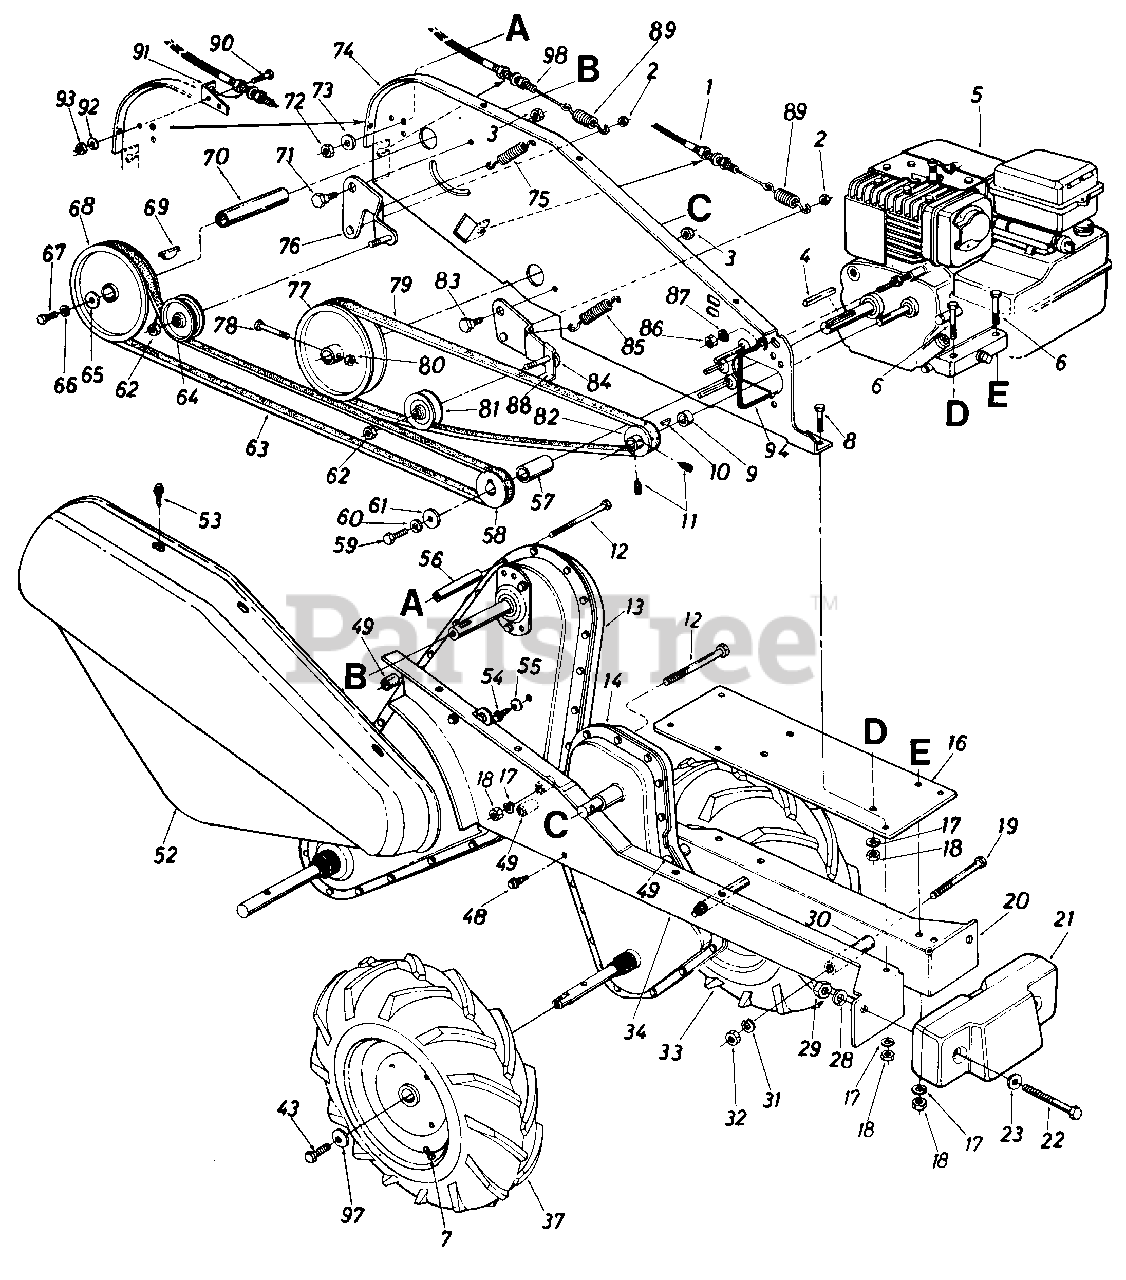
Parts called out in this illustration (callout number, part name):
1	Clutch Control Cable
2	Hex Cent. L-Nut 1/4-20 Thd.
3	Hex Cent. L-Nut 3/8-16 Thd.
4	Sq. Key 3/16" Dia. x .75
5	Engine
6	Hex Bolt 5/16-18 x 1.50" Lg.
7	Air Valve
8	Hex Bolt 5/16-18 x .75" Lg.
9	Spacer .51" I.D. x 3/4" O.D. x .39" Lg.
10	Hi-Pro Key #5 Woodruff
11	Set Scr. 1/4-28 x .25" Lg.
12	Hex Bolt 5/16-18 x 3.0" Lg.
18	Hex Nut 5/16-18 Thd.
19	Hex Bolt 3/8-24 x 3.0" Lg.
22	Hex Bolt 1/2-13 x 4.0" Lg.
23	Fl-Wash. 1/2" I.D. x 1.0" O.D.
28	L-Wash. 1/2" I.D.
29	Hex Nut 1/2-13 Thd.
30	Spacer 3/8" I.D. x 5/8" O.D. x 2.18" Lg.
31	L-Wash. 3/8" I.D.
32	Hex Nut 3/8-24 Thd.
33	Comp. Wheel Ass'y. L.H.
48	Hex Wash. Self-Tap Scr. 5/16-24 x .50" Lg.
49	Spacer 5/16" I.D. x 16 Ga. x.96" Lg.
54	Hex Wash. S-Tap Scr. 1/4-20 x 3/8" Lg.
55	Bell-Wash. 1/4" I.D.
56	Spacer 3/8" I.D. x 1/2" O.D. x 2.0" Lg.
57	Spacer 3/4" I.D. x 1.12" O.D. x 1.56" Lg.
58	1/2" "V"-4L Pulley 3/4n I.D. x 2.59" O.D.
59	Hex Bolt 5/16-24 x 1.0" Lg.
60	L-Wash. 5/16" I.D.
61	Fl-Wash. 5/16" I.D. x 1.25" O.D.
62	Hex L-Nut 3/8-24 Thd.
63	"V"-Belt
64	Fl-ldler Pulley 3.75" O.D. x 3/8" 1.D.
65	Fl-Wash. .25" I.D. x .93" O.D. x .120
66	L-Wash. 1/4" I.D.
67	Hex Bolt 1/4-28 x .75" Lg.
68	Split Pulley 6" Dia. x 5/8" I.D.
69	Hi-Pro Key
70	Spacer
71	Shld. Bolt 1/2" Dia. x .210n Lg.
72	Hex Nut 5/16-18 Thd.
73	L-Wash. 5/16" I.D.
74	Side Plate Ass'y.
75	Ext. Spring .50" O.D. x 1.55
76	Idler Bracket Ass'y. Tines
77	Pulley 6" Dia. x 5/8" I.D.
78	Hex Bolt 1/4-28 x 1.50" Lg.
79	"V"-Belt
80	Hex Cent. L-Nut 1/4-28 Thd.
81	"V"-ldler Pulley 2-518n O.D.
82	1/2" "V"-Pulley 21/4' O.D. x .50" I.D.
83	Shld. Bolt 1/2" Dia. x .160" Lg.
84	Idler Bracket Ass'y Wheels
85	Ext. Spring .50" O.D. x 1.55" Lg.
86	Hex Nut 1/4-20 Thd.
87	Bell-Wash. 1/4" I.D.
88	Belt Keeper Ass'y.
89	Ext. Spring
90	Hex Bolt 5/16-18 x .75"
91	Clutch Cable Brkt.
92	Lock Washer 5/16" I.D.
93	Hex Nut 5/16-18 Thd .
94	Belt Keeper
97	Bell-Wash. 5/16" I.D.
98	Clutch Control Cable
